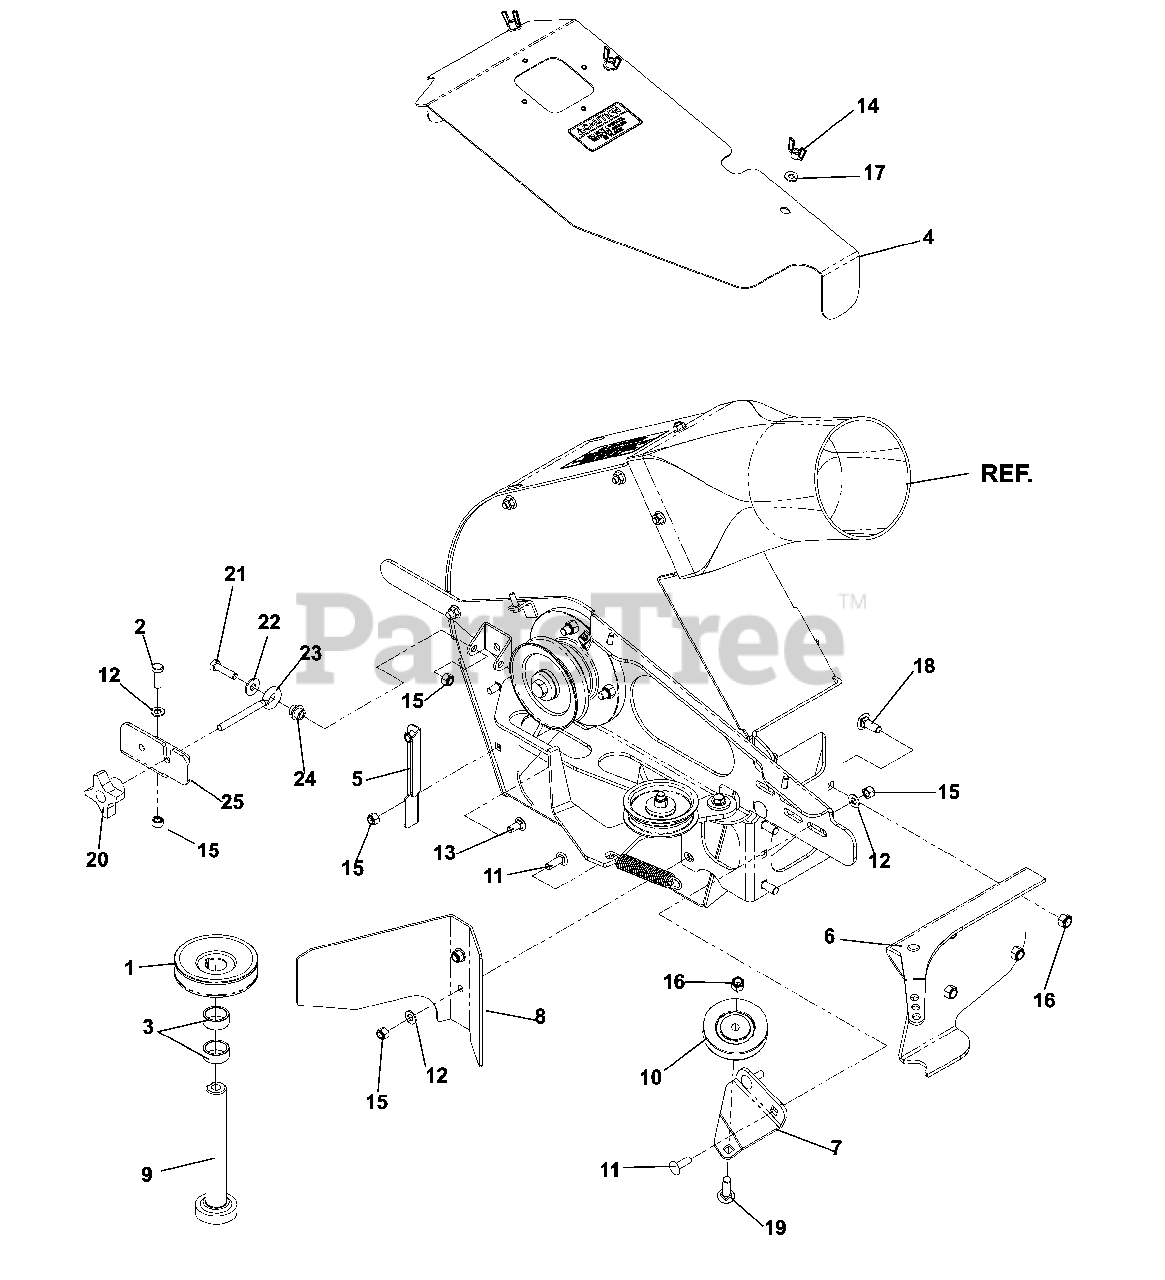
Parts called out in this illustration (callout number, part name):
1	V-PULLEY
2	HCS 5/16C X 1
3	HUB BEARING SPACER
4	GUARD ASSEMBLY. 52"
6	PIVOT WLDT
7	FIXED IDLER BRKT.
8	BLOCK OFF PLATE
9	SHAFT LONG
10	PULLEY, IDLER 3 METAL
11	RHSSNB 5/16C X 1.0
12	FLAT WASHER 5/16 SAE
13	BOLT 5/16C X 3/4" CARRIAGE
14	WING NUT 1/4
15	NUT 5/16 NYLOC
16	NUT 3/8-16 NYLOC
17	1/4` SAE FLAT WASHER
18	RHSNB 3/8C X 1
19	RHSNB, 3/8-16 X 1-1/2
20	SEAT KNOB 5/16-18
21	HCS 5/16C X 1 1/4
22	WASHER 5/16 FLAT
23	EYE BOLT 5/16 X 3.50
24	SPRING CAP
25	LATCH RECEIVER
